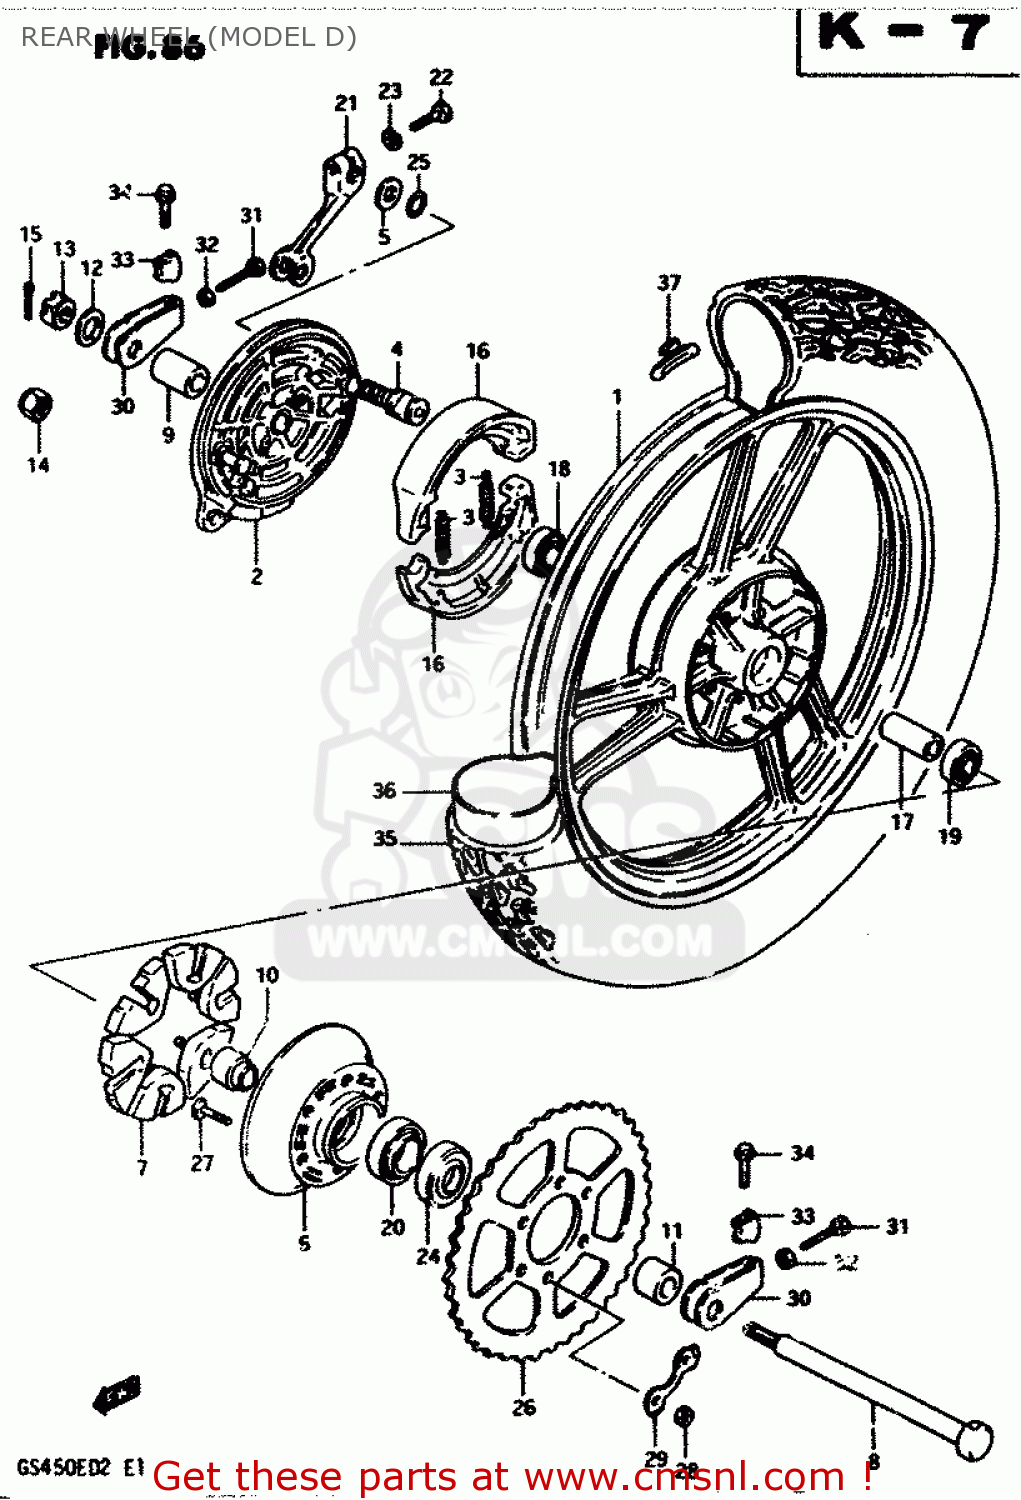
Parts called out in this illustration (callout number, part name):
1	WHEEL, REAR (18X1.85)
2	PANEL,REAR HUB
3	SPRING,BRAKE SHOE
4	CAM,FRONT BRAKE
5	WASHER (15X24X1.6)
6	DRUM,REAR SPROCKET MOUNT
7	ABSORBER,RR HUB SHOCK
8	AXLE,REAR
9	SPACER(17.5X28X44.8)
10	SPACER,REAR HUB BEARING
11	SPACER(17X30.5X22.3)
12	WASHER (17X30X3.2)
13	NUT
14	NUT
15	PIN,COTTER
16	SHOE,BRAKE
17	SPACER (17.6X24X57)
18	BEARING
19	BEARING
20	BEARING
21	LEVER,RR BRAKE CAM
22	BOLT
23	LOCK WASHER
24	SEAL,OIL(30.5X52X8)
25	O-RING,BOSS
26	SPROCKET,RR
27	BOLT
28	NUT
29	WASHER
30	ADJUSTER,CHAIN
31	BOLT 8X50
32	NUT
33	SUPPORTER,CHAIN ADJUST
34	BOLT
35	TIRE
36	TUBE ASSEMBLY,WHEEL,INNER
37	BALANCER,WHEEL
